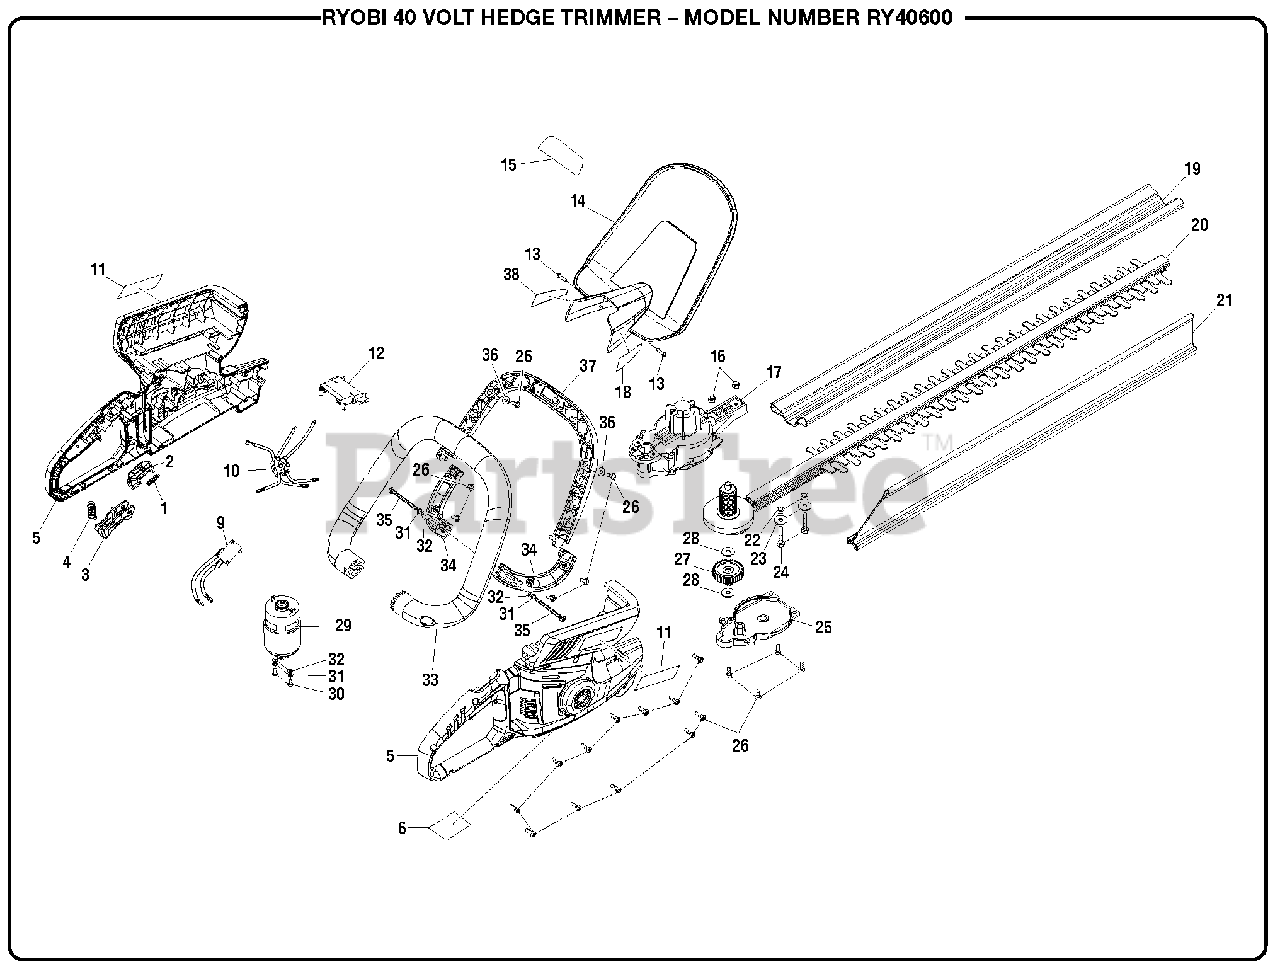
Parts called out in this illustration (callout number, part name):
1	Compression Spring
2	Lock Off Button
4	Compression Spring
5	Housing Assembly
6	Data Label
9	Micro Switch
10	Wire Terminal Assembly
12	Battery Connector Assembly
13	Screw (M2.9 x 12 mm)
15	Warning Label
16	Hex Nut (M5)
17	Gear Box Assembly
18	Lithium Label (Right)
19	Blade Shield
20	Blade, Cam, and Clutch Assembly
21	Debris Remover
23	Washer (OD16 x ID5.2 x 1.5t)
24	Screw (M5 x 30 mm)
25	Gear Box Cover
26	Screw (M4 x 12 mm)
27	Dual Gear
28	Washer (ID6.2 x OD14 x 0.5t)
29	Motor and Pinion Assembly
30	Screw (M4 x 10 mm)
31	Spring Washer (M4)
32	Flat Washer (M4)
33	Auxiliary Handle
34	Lower Auxiliary Handle Cover Assembly
35	Screw (M4 x 50 mm)
37	Upper Auxiliary Handle Cover
38	Lithium Label (Left)
